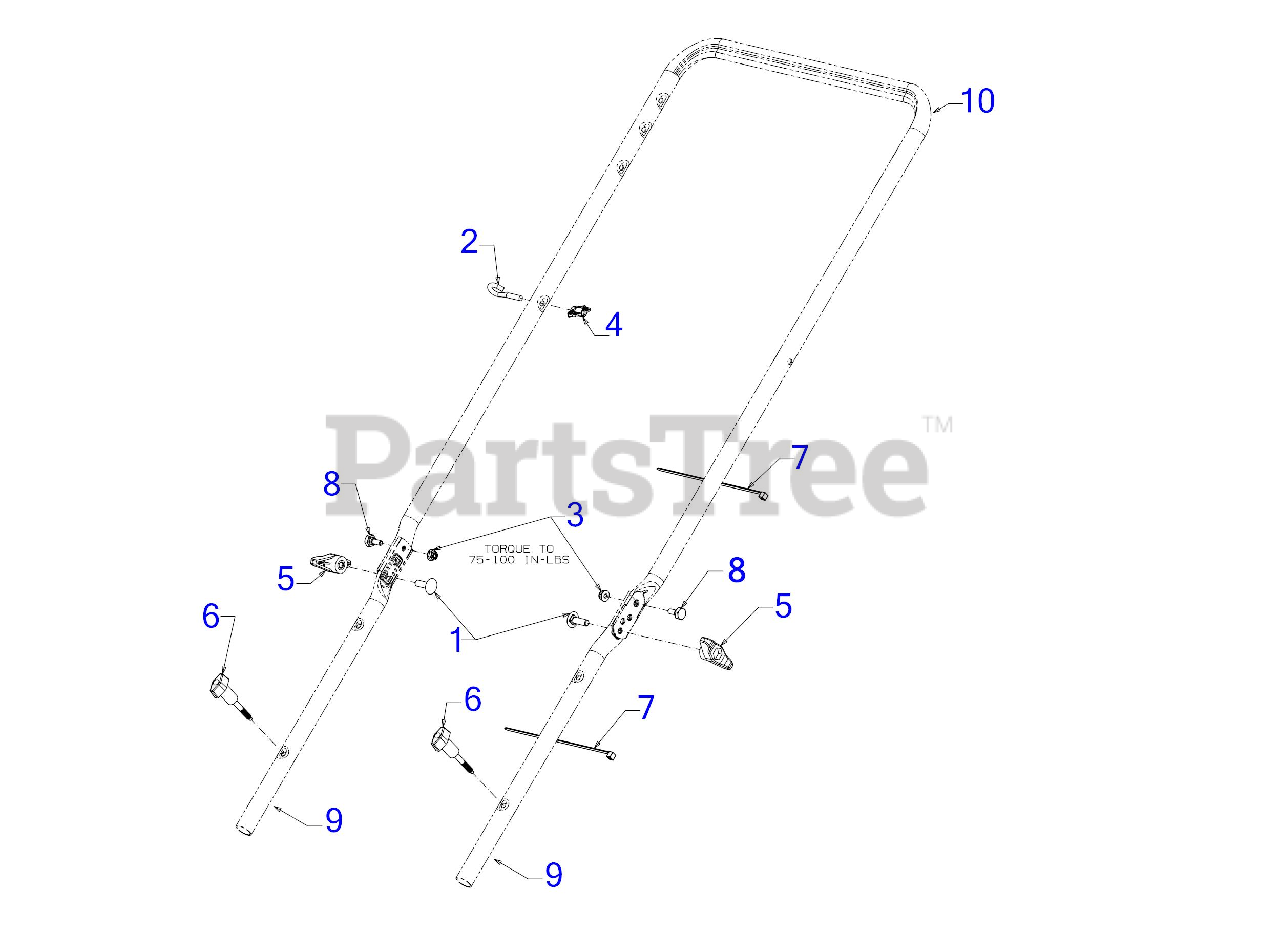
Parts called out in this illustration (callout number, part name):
1	SCREW 5/16-18 x 1.00 GR5
2	EYEBOLT 1/4-20
3	FLANGE LOCK NUT
4	HANDLE KNOB
5	WING KNOB 5/16-18
6	WING KNOB 1/4-20
7	7" CABLE TIE
8	SHOULDER SCREW
9	LOWER HANDLE
10	NON ADJUST UPPER HANDLE
